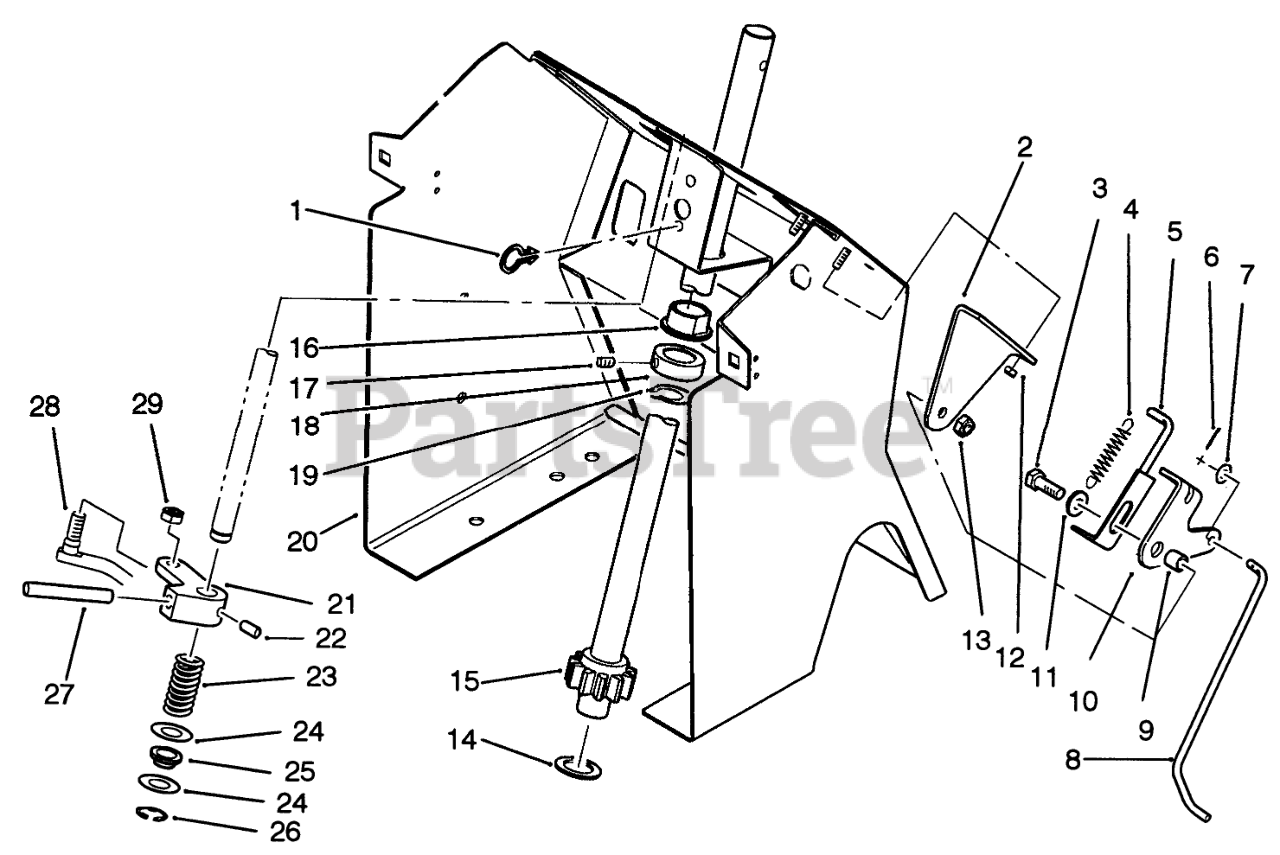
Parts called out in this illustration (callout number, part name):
1	CLIP-SNAP IN
2	Nut
3	SCREW-HH
4	SPRING-EXTENSION
5	WLDMT-INDICATOR R
6	Cotter Pin
7	WASHER-FLAT
8	ROD-INDICATOR
9	SPACER
10	RETAINER-INDICATO B
11	WASHER-FLAT
12	SUPPORT-INDICATOR B
13	NUT-LOCK, NI
14	WASHER
15	WLDMT-STRG SHAFT
16	COLLAR
17	SCREW-HSH
18	BEARING-FLANGED
19	RING-RETAINING
20	Hood Stand
21	ARM-SPEED CONTROL
22	Pin-Roll
23	SPRING-COMPRESSION
24	SHIM-WASHER
25	BUSHING-NYLINER
26	RING-SHAFT, EXT
27	PIN-SPIROL 5/16X2.25
28	ROD-SHIFT R
29	NUT-LOCK, NI
